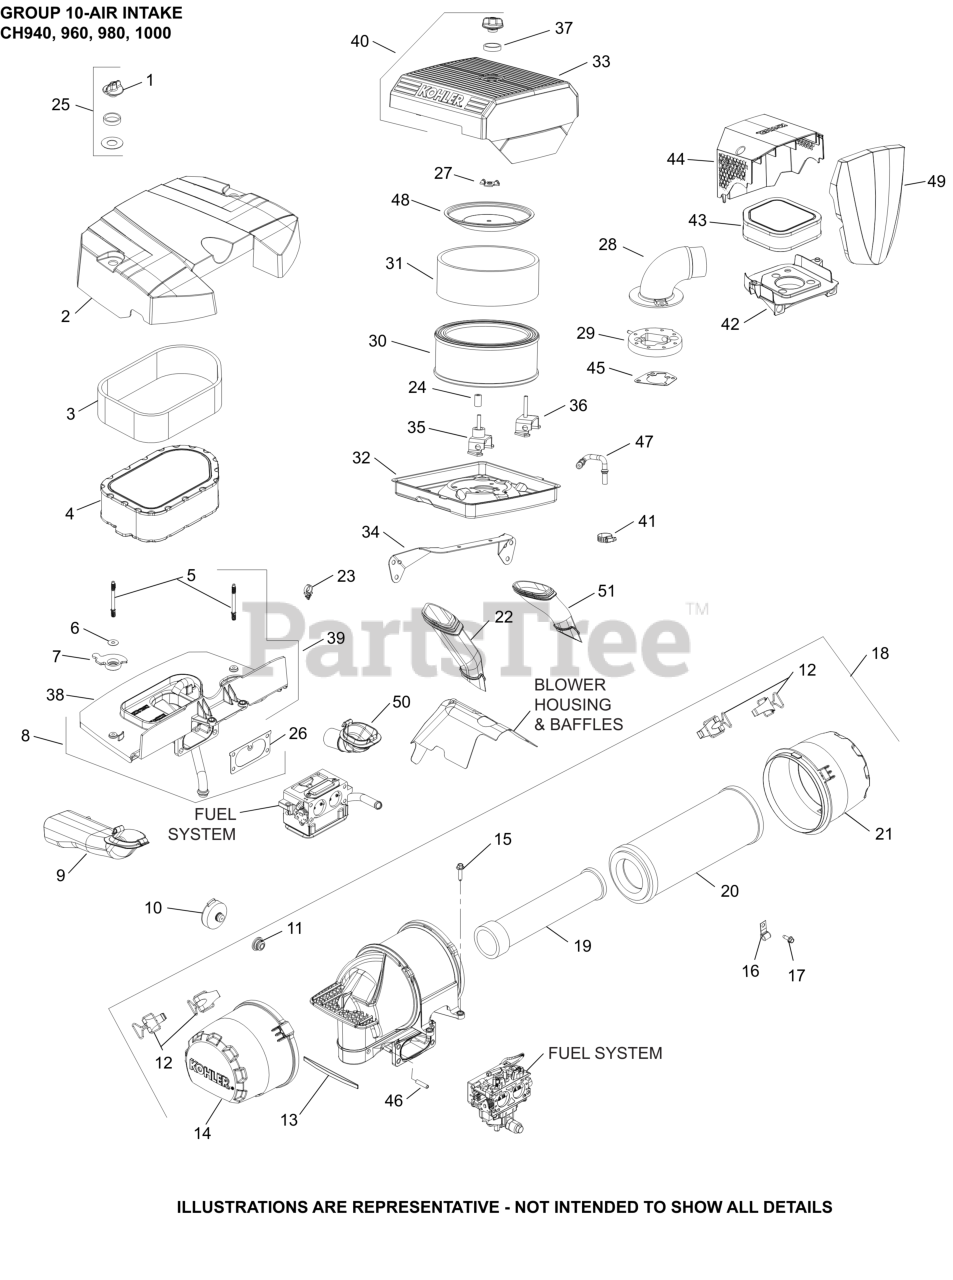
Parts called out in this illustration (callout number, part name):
11	PLUG, HOLE
12	CLIP ASSEMBLY
13	DAMPER, FOAM INSERT
14	COVER, RAIN CAP
15	SCREW, FLG M6X1.0X25
17	SCREW, THREAD FORMING
18	KIT, AIR CLEANER
19	ELEMENT, AIR FILTER - SAFETY
20	ELEMENT, AIR FILTER - PRIMARY
21	COVER, AIR FILTER
